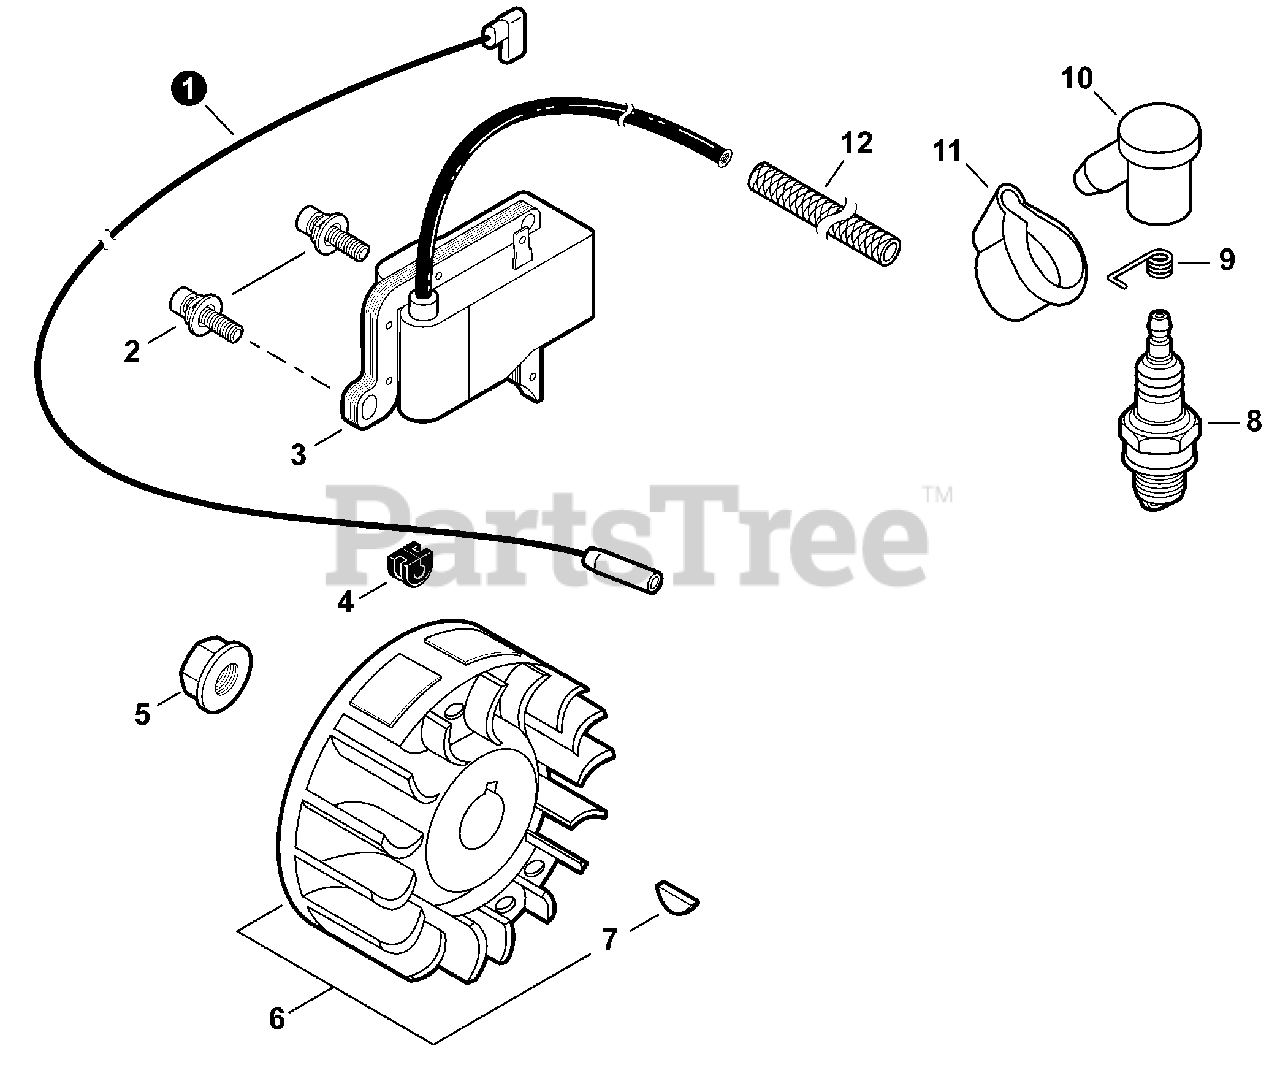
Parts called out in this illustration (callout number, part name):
1	LEAD 170MM
2	BOLT 5×20
3	COIL, IGNITION
5	NUT, FLANGE 10×1.25
6	FLYWHEEL KIT
7	KEY, WOODRUFF 3×14
8	SPARK PLUG - BPMR7A
9	TERMINAL, SPARK PLUG
10	CAP, SPARK PLUG
11	COVER, DUST
12	TUBE, INSULATOR 7×8.6×55
